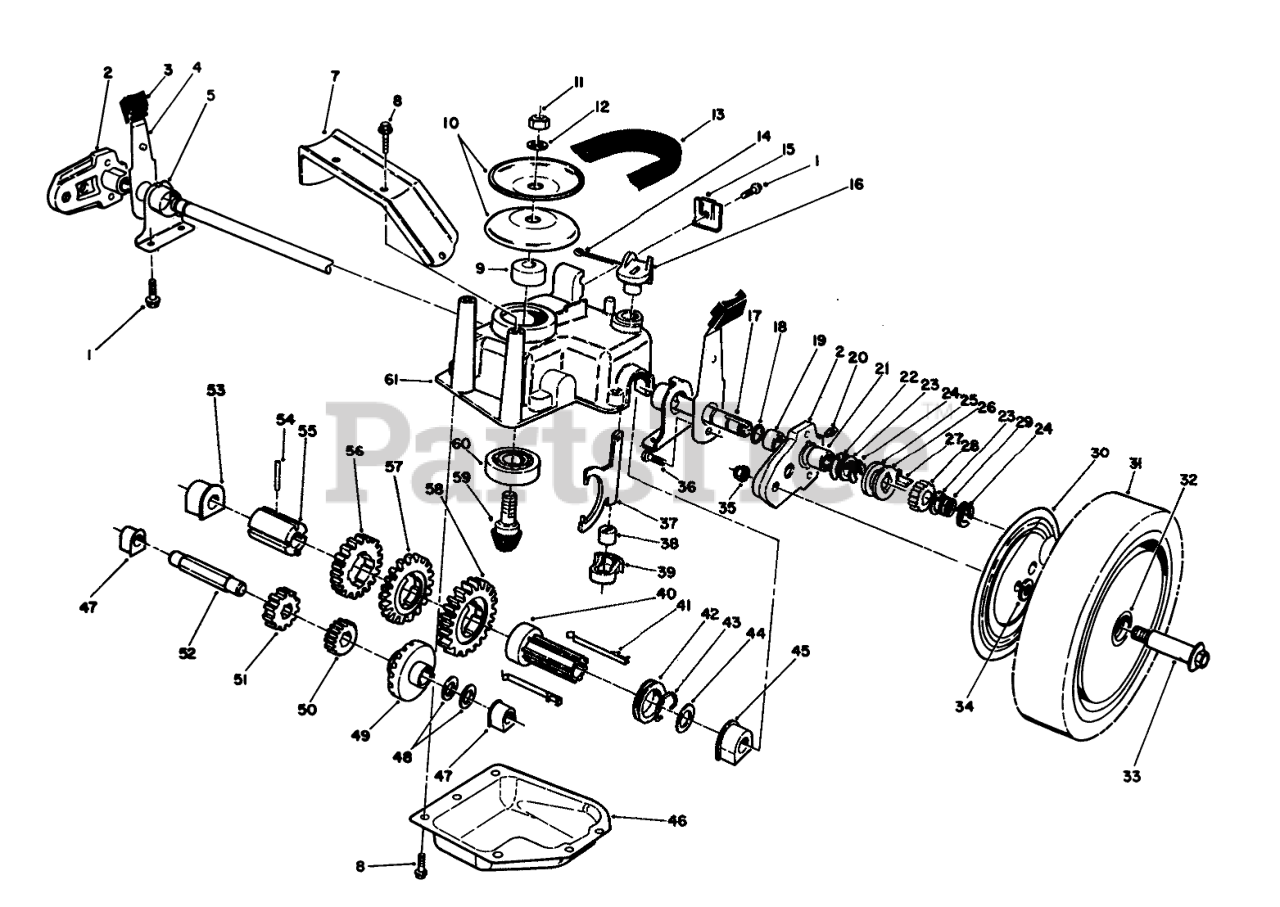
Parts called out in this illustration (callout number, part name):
1	SCREW-HWHTF
2	Pivot Arm Assembly (Incl. Ref. #19-21)
3	KNOB-ARM
4	SPRING ARM ASM
5	CAP-END
7	Bracket-BeltGuide
8	SCREW-HWHTF
9	SPACER
10	Pulley Half
11	NUT-HEX
12	WASHER-FLAT
13	V-BELT
14	PIN-COTTER
15	CABLE CLAMP
16	Lever-Shift
17	SHAFT-OUTPUT
18	O-RING
19	BUSHING
20	FITTING-GREASE
21	BEARING-ROLLER
22	WASHER-ARM, PIVOT
23	WASHER-THRUST, KEYED
24	RING-CLIP, LOCKING
25	RING-FRICTION
26	WASHER-CLUTCH
27	KEY-ROCKING, LH
28	GEAR-PINION
29	SPRING-COMPRESSION
30	WHEEL COVER
31	Wheel Tire & Gear Assy. (Incl. Ref. #32)
32	BUSHING
33	WHEEL BOLT
34	WASHER
35	Nut
36	SCREW-HSH, THREAD FORMING
37	YOKE-SHIFT
38	BUSHING-YOKE
39	RETAINER-FORK, SHIFT
40	SHIFT KEY SLEEVE
41	SHIFT KEY
42	SHIFT COLLAR
43	CLIP-SPRING
44	WASHER-PLAIN
45	BUSHING-OUTPUT
46	Cover-Gearcase
47	BUSHING
48	WASHER-THRUST
49	Gear-Bevel
50	PINION-20T
51	PINION-25T
52	SHAFT-INTERMEDIATE
53	bushing-Output Shaft
54	PIN-SPRING
55	SLEEVE-GEAR
56	GEAR-39T
57	GEAR-44T
58	GEAR-49T
59	Gear-Pinion
60	BEARING-BALL
61	CASE-GEAR, UPPER
